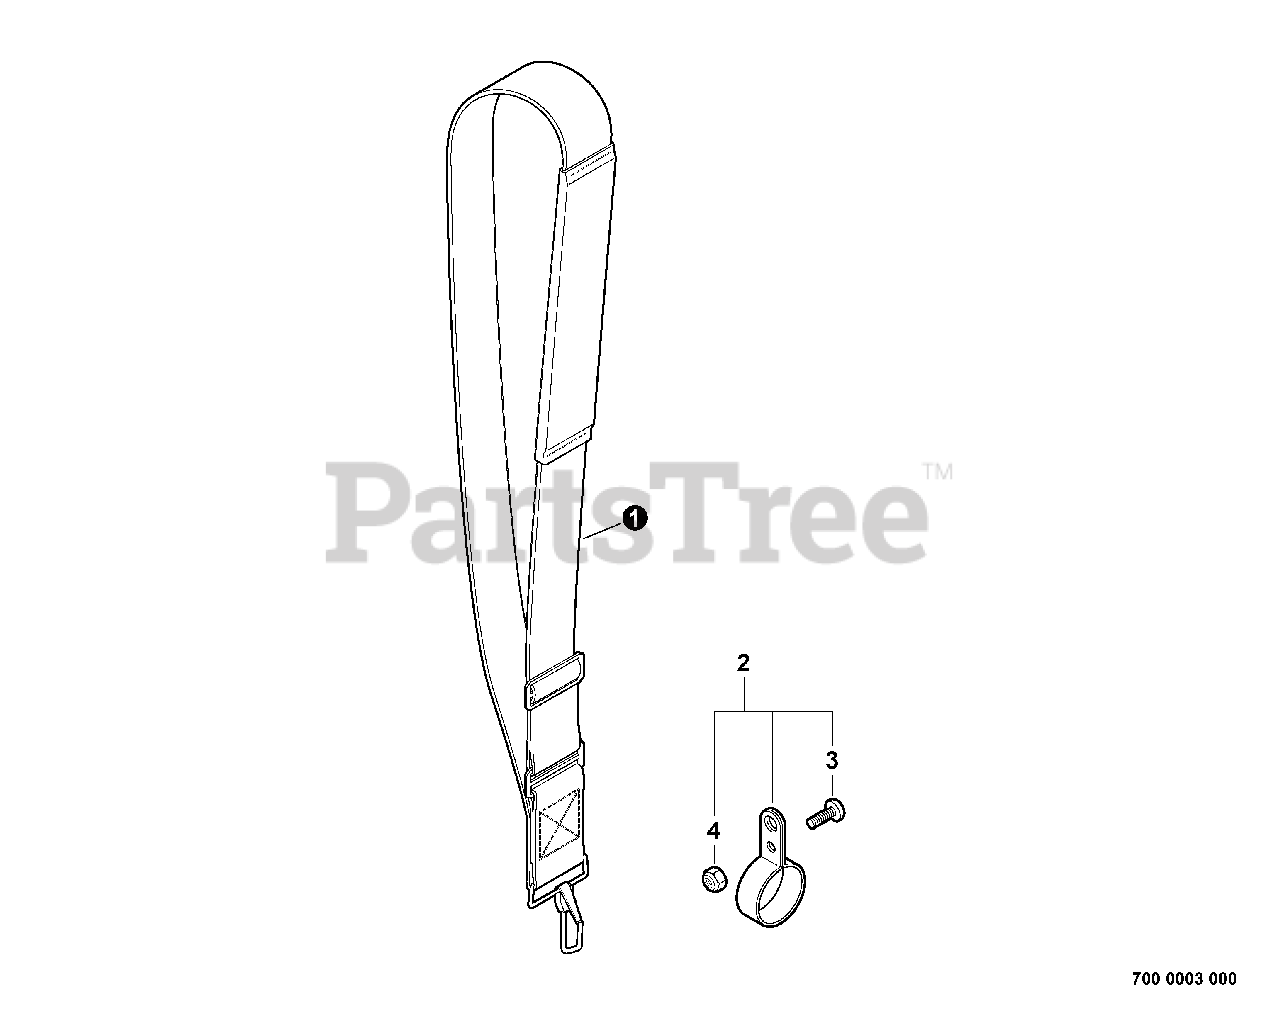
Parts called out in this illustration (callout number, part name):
1	SHOULDER STRAP ASSY
2	HANGER KIT
3	SCREW
4	LOCKNUT - 10-24
